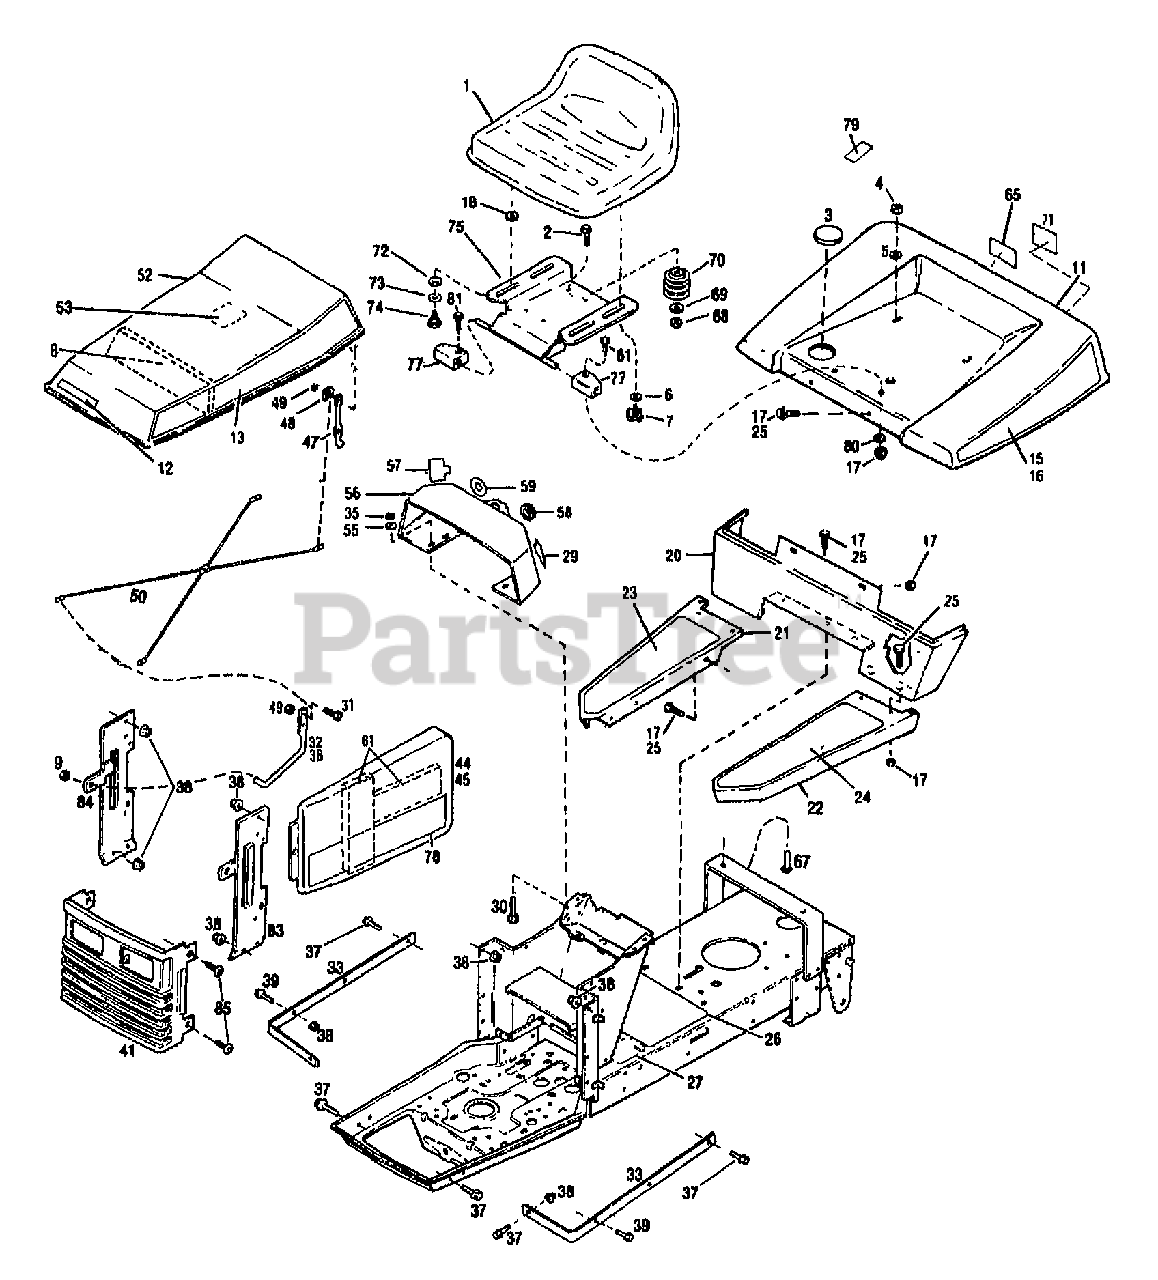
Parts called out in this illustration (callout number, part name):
1	SEAT {13064}
1	SEAT {13065,13066}
2	SCR-HFLK 3/8-16X1.00 ZP
4	NUT-TOP/LK 5/16-18 ZP
5	WASHER-1.25X.343X.059 {13065,13066}
6	WASHER-FLAT 3/8 SAE
8	FOAM-UPPER {13065,13066}
9	NUT-SPECIAL
11	FENDER-REAR
12	DECAL-LOGO
13	DECAL-LOGO
15	DECAL-FENDER {13066}
15	DECAL-FENDER RH RED {13065}
15	DECAL-FENDER RH {13064}
16	DECAL-FENDER LH {13066}
16	DECAL-FENDER LH RED {13065}
16	DECAL-FENDER LH {13064}
17	NUT-HFLK 5/16-18 ZP
18	WASHER-FLAT
20	SUPT-RUNNING BOARD
21	BOARD-RUNNING RH
22	BOARD-RUNNING LH
23	PAD-FOOT RH
24	PAD-FOOT LH
25	SCR-LOCK
26	PAD-FOOT
27	DECAL-OPERATING INST
29	DECAL-CHOKE {13064}
29	DECAL-CHOKE {13065,13066}
30	SCR-HH 1/4-20X.625 G5 ZP
31	SCR-HHS 10-24X.625 ZP
32	LINK-HINGE RH
33	ASSM-HINGE STRAP
35	NUT-HT/LK 1/4-20
36	LINK-HINGE LH
37	SCR-HH 1/4-20X.625
38	NUT-HF/LK 1/4-20 ZP
39	SCR-HFLK 1/4-20X.50 ZP
44	COVER-SIDE LH
45	COVER-SIDE RH
47	LATCH-RUBBER
49	NUT W/LKWASHER 10-24 ZP
50	SUPPORT-HOOD ROD
52	ASSM-HOOD
53	DECAL-SVC INST
55	WASHER-FLAT 1/4 SAE
56	PANEL-INSTRUCTION
57	DECAL-THROTTLE
58	CAP {13064}
59	DECAL-IGNITION
61	BLOCK-SEALING {13065,13066}
65	DECAL-FUEL
67	SCR-CARR 5/16-18X.75
68	NUT-HFLK 3/8-16 ZP
69	WASHER-FLAT 1.25X.406X.179
70	SPRING-COMPRESSION
71	DECAL-LOGO FENDER
72	WASHER-BOW .74X.52X.01
73	WASHER-1.06X.51X.09 NYLON
74	SCR-SHLDR 3/8-16X.25 G5ZP
75	ASSM-SEAT SUPPORT
77	BLOCK-PIVOT
78	DECAL-SIDECVR LH RED
78	DECAL-SIDECVR RH RED
79	DECAL-U.S.A.
80	WASHER-1.5X.343X.104
81	SCR-HH 5/16-18X1.5 G5 ZP
83	ASSM-SUPPORT LH
84	ASSM-SUPPORT RH
